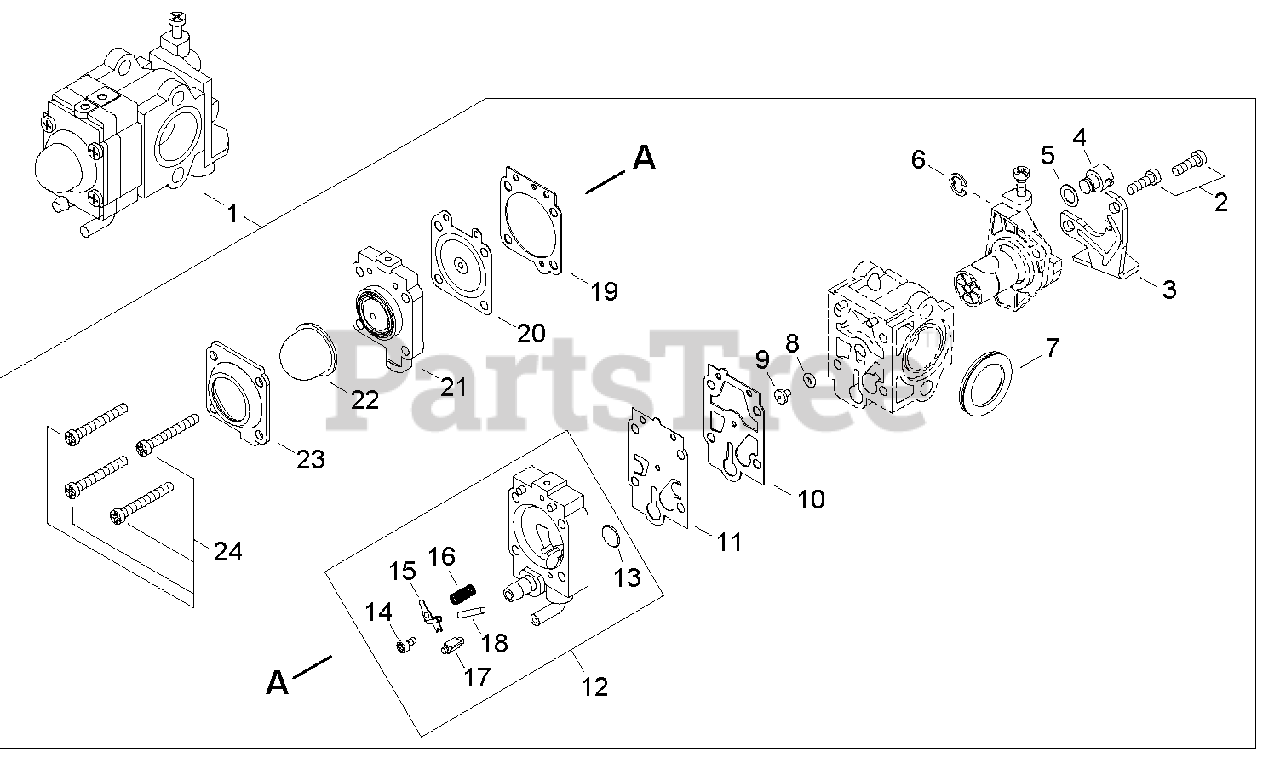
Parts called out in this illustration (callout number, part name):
1	CARBURETOR WYJ-488
3	BRACKET, THROTTLE CABLE
6	RING, RETAINING
9	JET, MAIN
10	GASKET, PUMP
11	DIAPHRAGM, PUMP
12	BASE, PURGE
13	STRAINER
14	SCREW, METERING LEVER PIN
15	LEVER, METERING
16	SPRING, METERING LEVER
17	VALVE, INLET NEEDLE
18	PIN, METERING LEVER
19	GASKET, METERING
20	DIAPHRAGM, METERING
21	PURGE BASE ASSY
22	BULB, PURGE
23	RETAINER, PURGE BULB
24	SCREW, PUMP COVER
